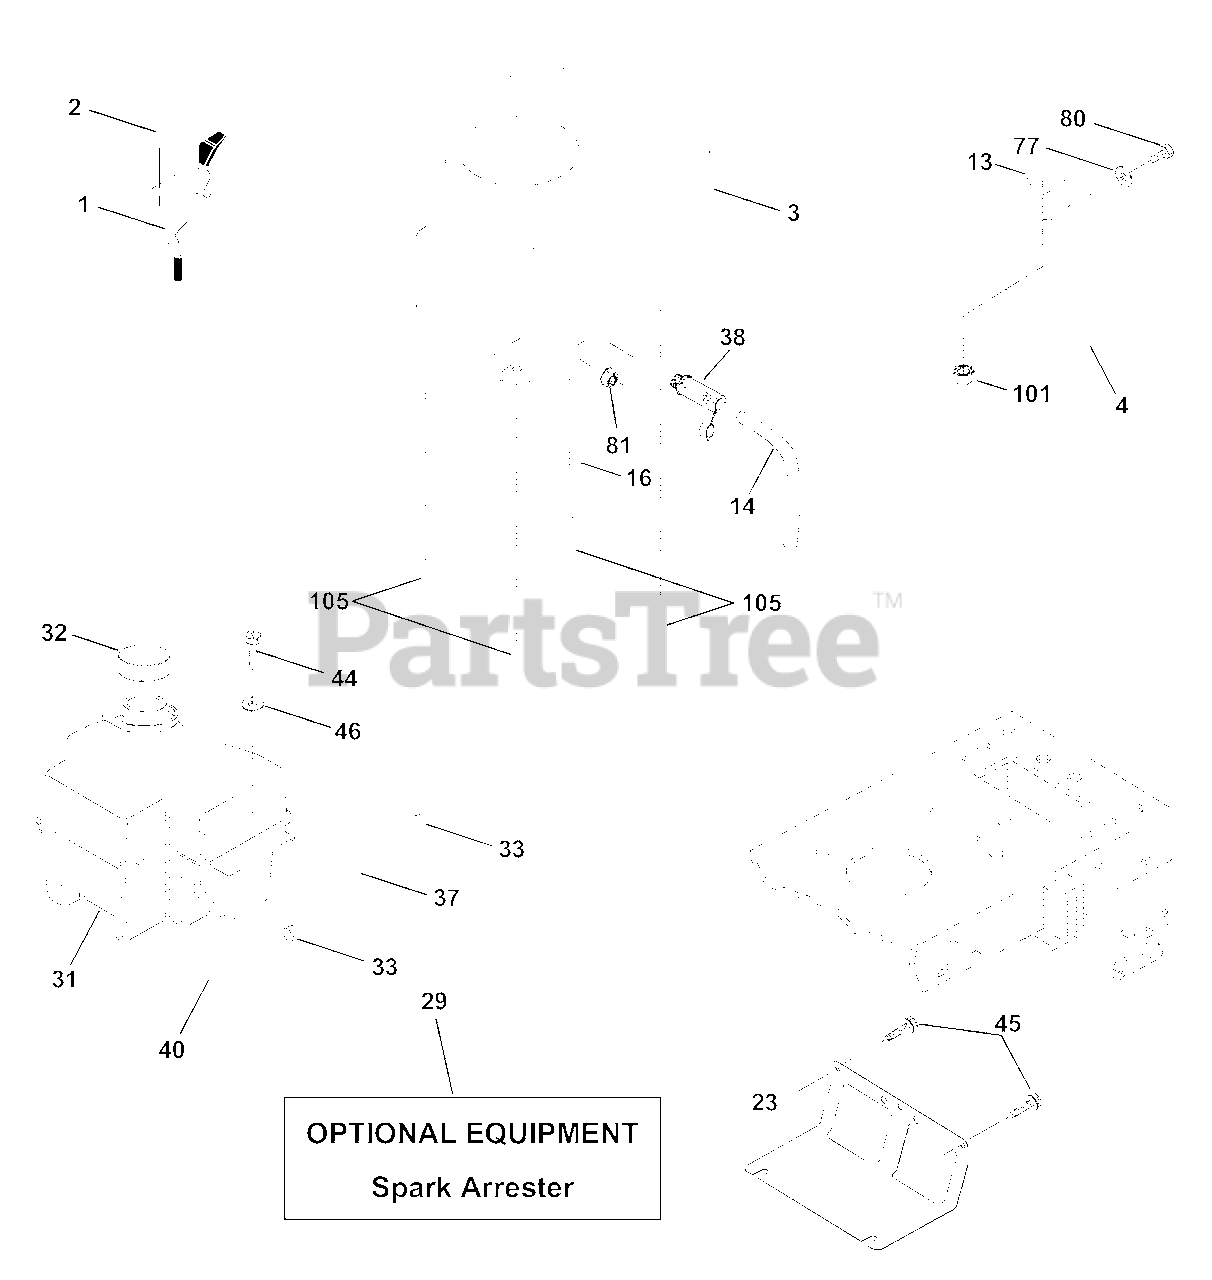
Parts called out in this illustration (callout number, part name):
1	Control Th/ch Flag
2	Screw Hex Thd Cut 1/4-20x5/8 T
4	Muffler Exhaust
13	Gasket Muffler
14	Tube Drain Oil Easy
16	Washer Lock Ext Tooth 3/8
23	Shield Brn/Dbr Guard
29	Arrestor Spark
31	Tank Fuel Front 2 00
32	Cap Fuel
33	Clamp Hose Black
37	Line Fuel 20"
38	Plug Drain Oil Easy
40	Bushing Snap Nyl Blk Fuel Line
44	Screw Hex wsh Thdrol 1/4-20x3/4
45	Screw Hex Wsh Thdrol 3/8-16 x 3/4
46	Washer 9/32 X 7/8 X 16 Ga
62	Washer Lock Hvy Hlcl Spr 5/16
72	Screw Hex Hd Cap 5/16-18 x 3/4
77	Washer 5/16 x 3/4 x 16 Ga.
78	Screw 3/8-16 x 1-1/4
80	Bolt Hex Hd. 5/16-18 Unc x 1/2
81	Nut Keps Hex 1/4-20 Unc
101	Nut Flange
105	Screw 3/8-16 x 1
